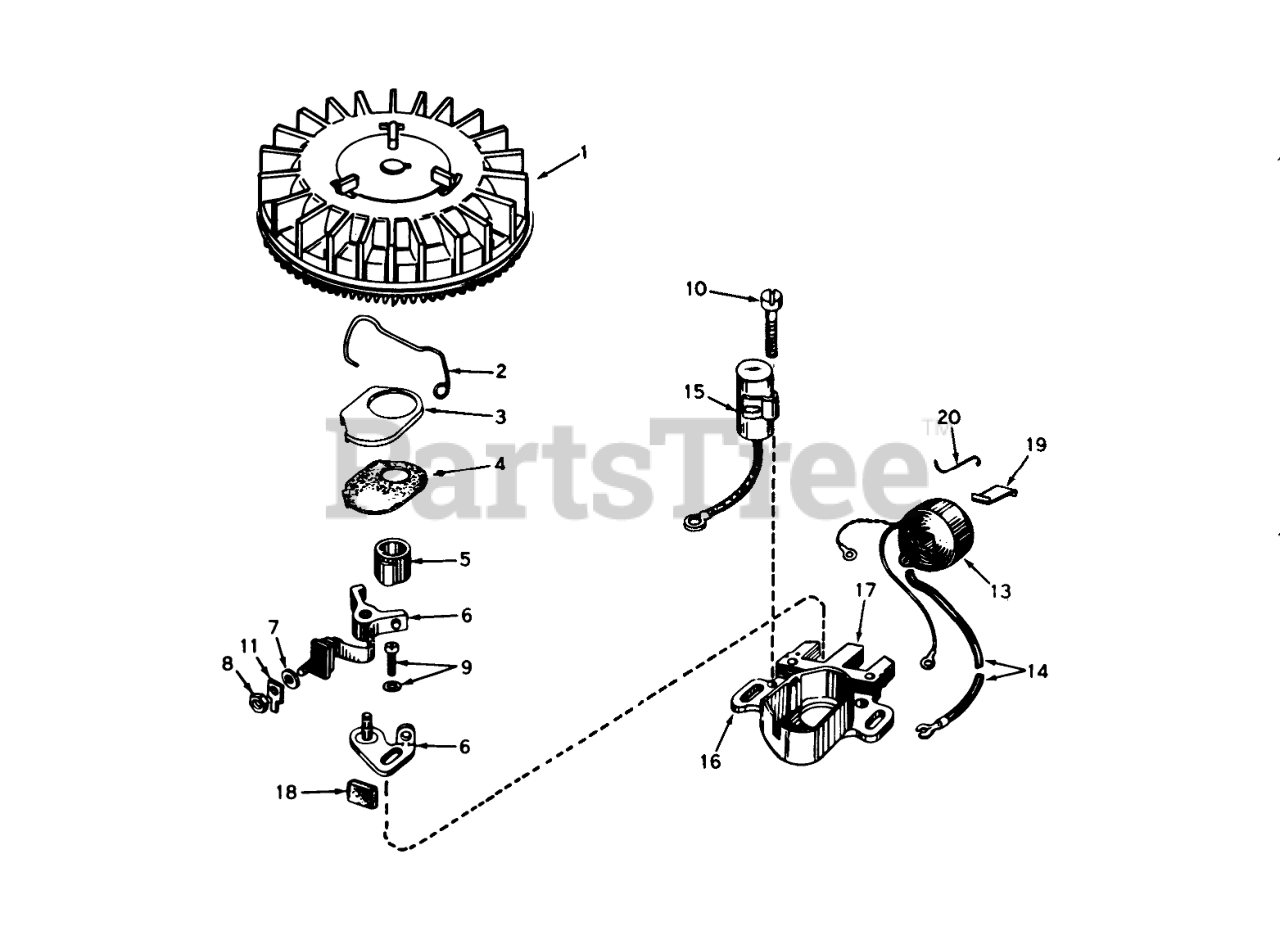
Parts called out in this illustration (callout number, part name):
1	Flywheel (Incl. Ref. #3 & 4)
2	Spring Breaker Box
3	Cover-Dust
4	Gasket, Dust Cover
5	Cam, Breaker
6	Breaker Assy.
9	Breaker Screw
10	Condenser Screw
11	Terminal, Ground
13	Coil Assy. (Incl. Ref. #14)
14	Wire, Lead
15	Condenser
16	Core & Plate
17	Stator Assy. (Incl. Ref. #2, 3, 4, 6, thru 16, 18, 19 & 20)
18	Felt,Cam Wiper
19	Spring Coil Wedge
20	Clip, Coil
